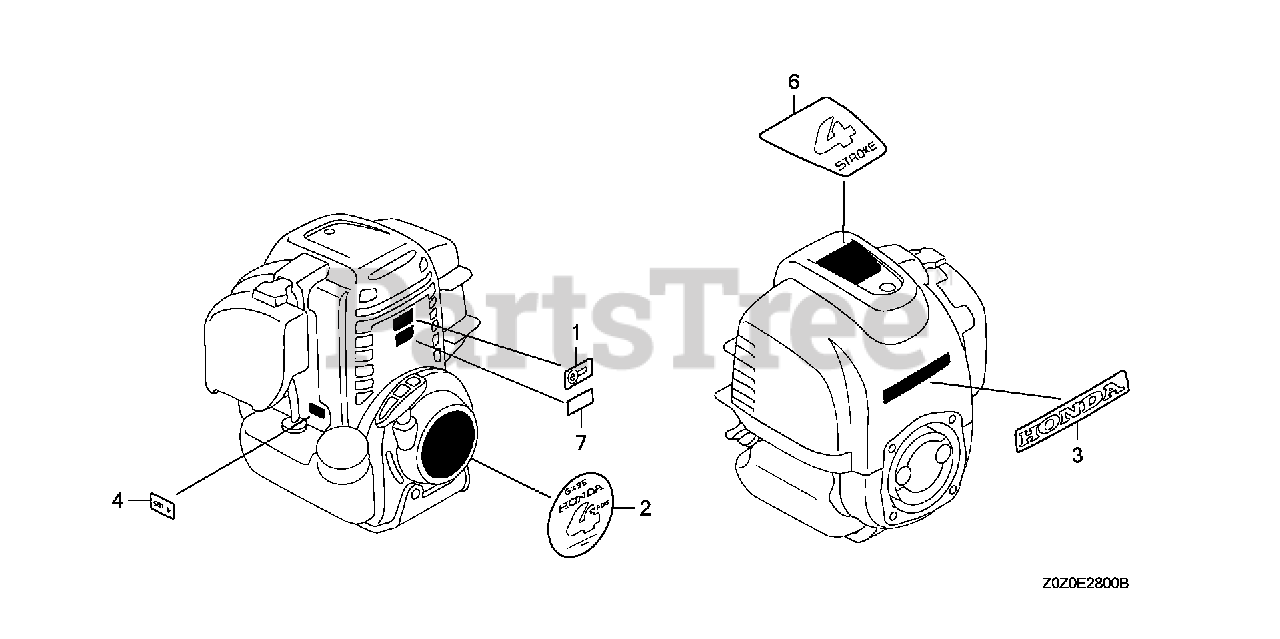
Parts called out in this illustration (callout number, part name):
2	MARK, EMBLEM
3	MARK, HONDA
4	MARK, TYPE (SAT)
6	MARK (4-STROKE)
